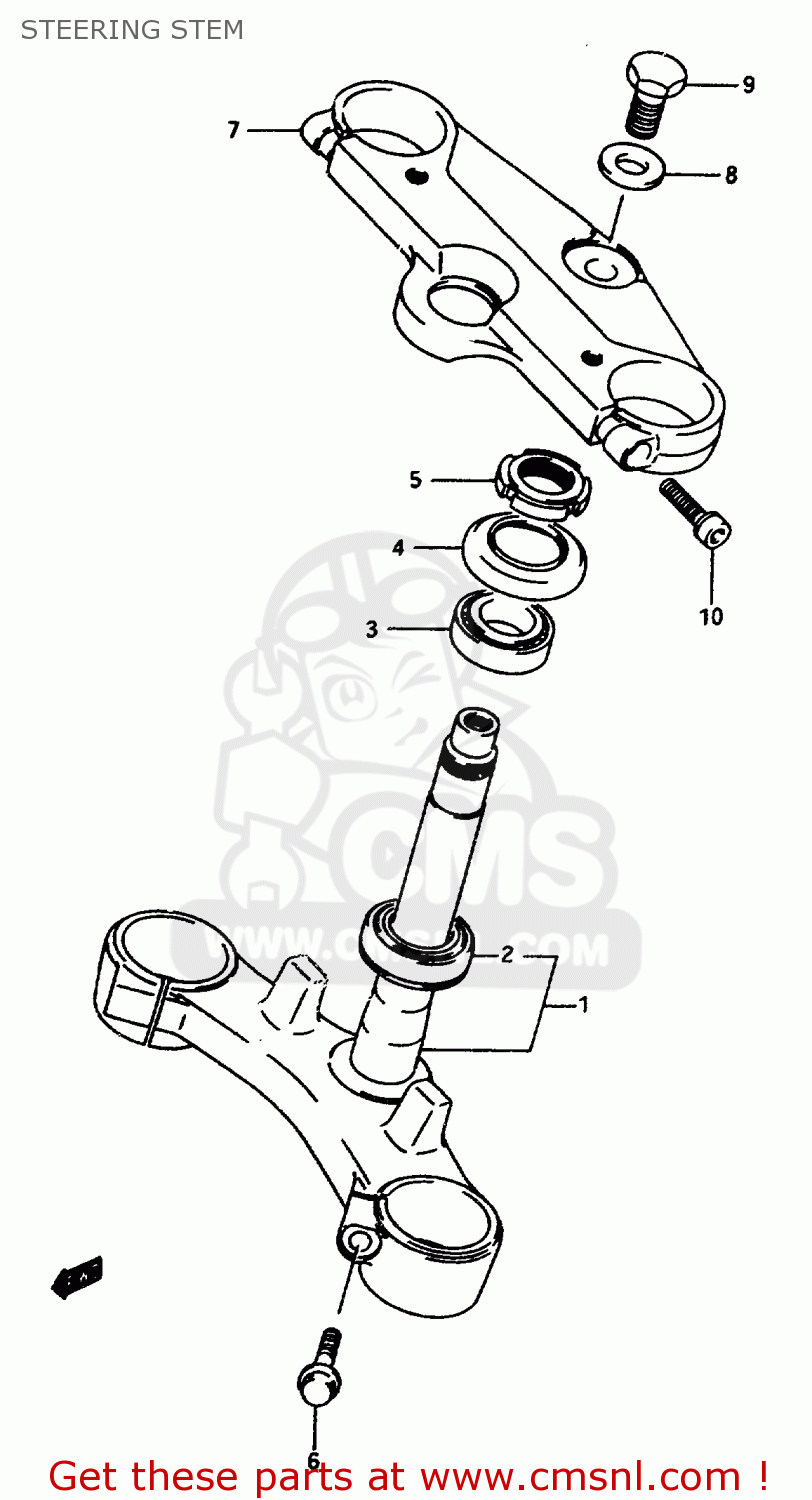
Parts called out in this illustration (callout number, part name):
1	STEM,STEERING
2	BEARING(30X55X17)
3	BEARING(25X47X15)
4	SEAL,STEERING UPR DUST
5	NUT,STEERING STEM(25X44X10)
6	BOLT
7	HEAD,STEERING STEM
8	WASHER,STEERING STEM
9	BOLT,STEERING STEM HEAD
10	BOLT
